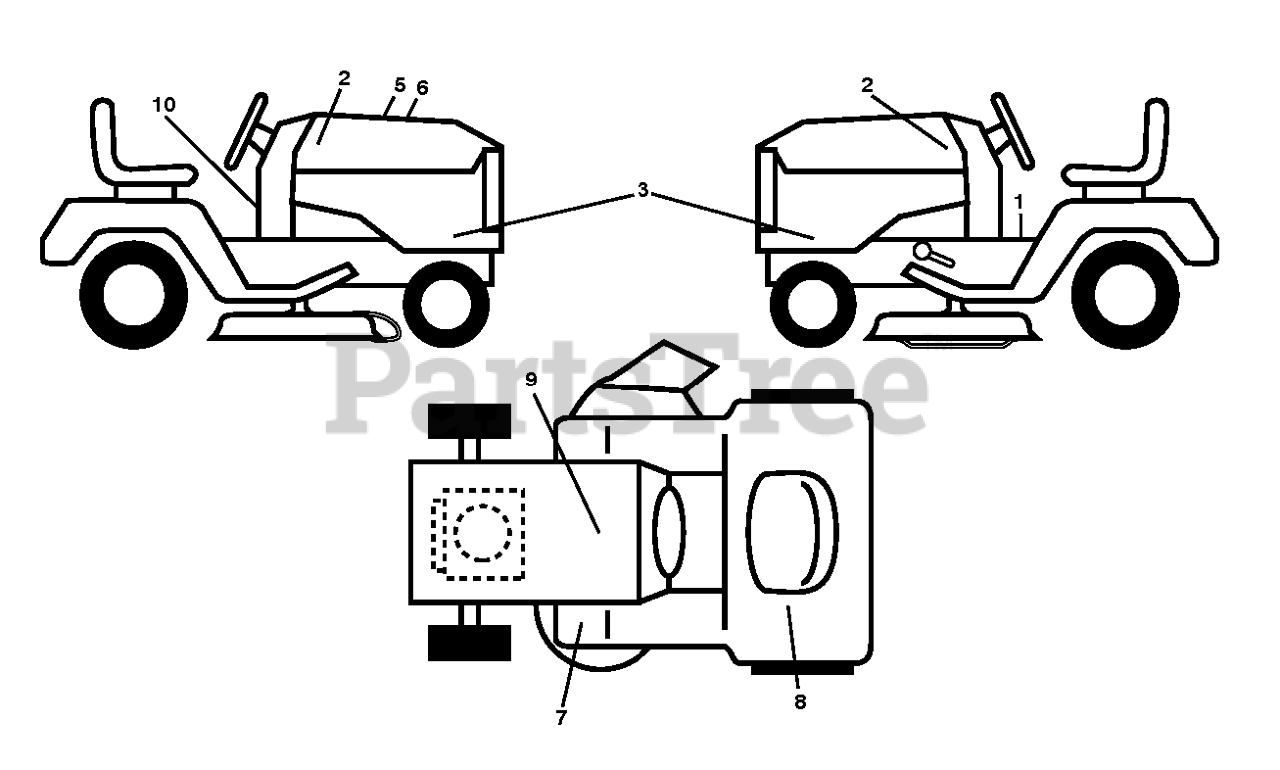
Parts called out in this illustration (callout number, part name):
1	DECAL.FENDER.WARNING.ENG
2	DECAL.BADGE.170MM.TEXTLOGO.
3	DECAL.SDPNL.HUSQGT2.MS668.YTH2
5	DECAL.WARNING.CUST.RESP.E85.
6	DECAL.REPLACEMENT.960480014
7	DECAL.PEDAL.HUSQ.CROWN
8	DECAL.WARN.RESERVE.FUEL
9	DECAL BTRY SYMBOLS
